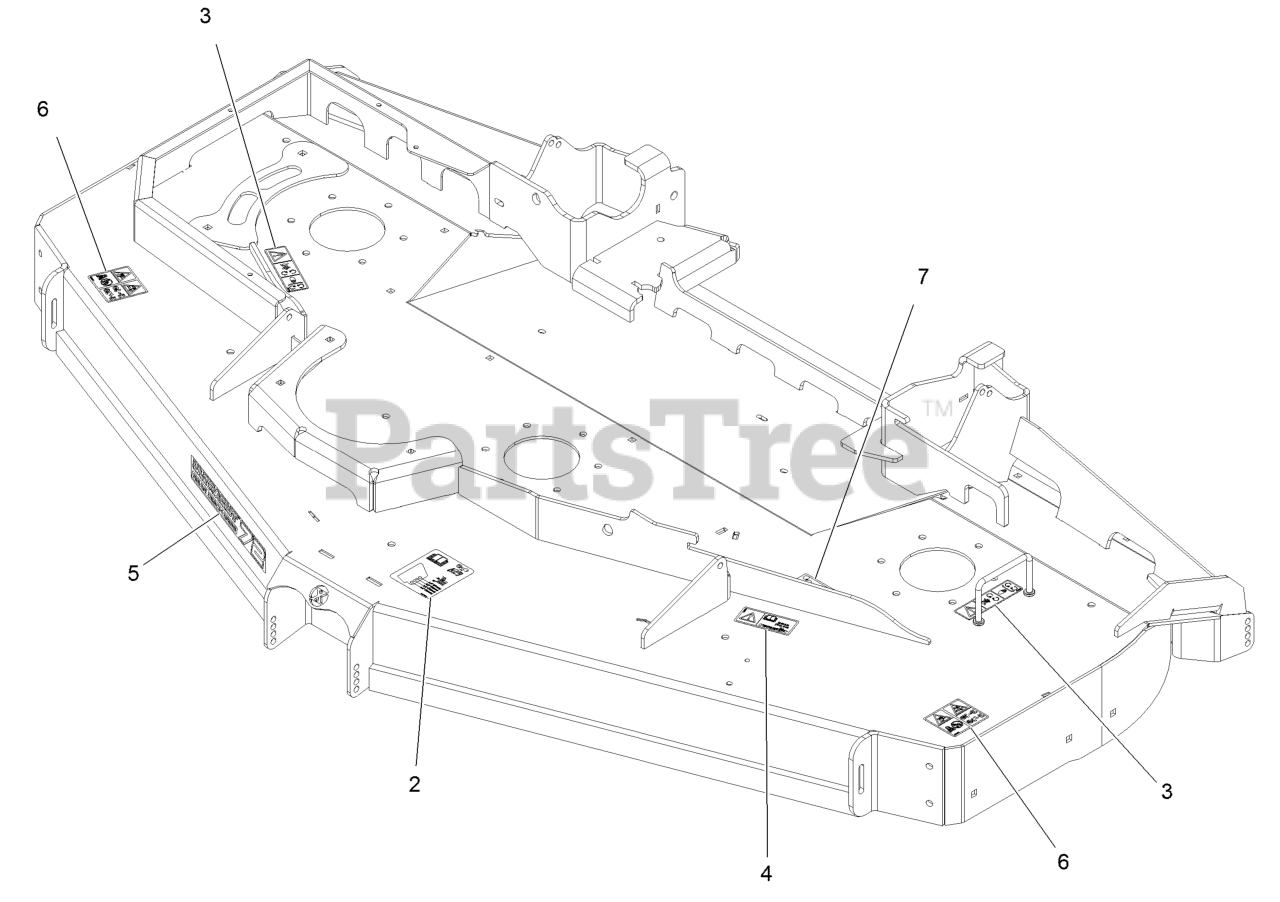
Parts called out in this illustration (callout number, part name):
2	Decal-Roller, Anti-Scalp
3	Decal-Cover, Missing
4	Decal-Bolt Torque
5	Decal, 72Rd
6	Decal-Danger, Thrown Object
7	Decal-Belt Routing Rear
